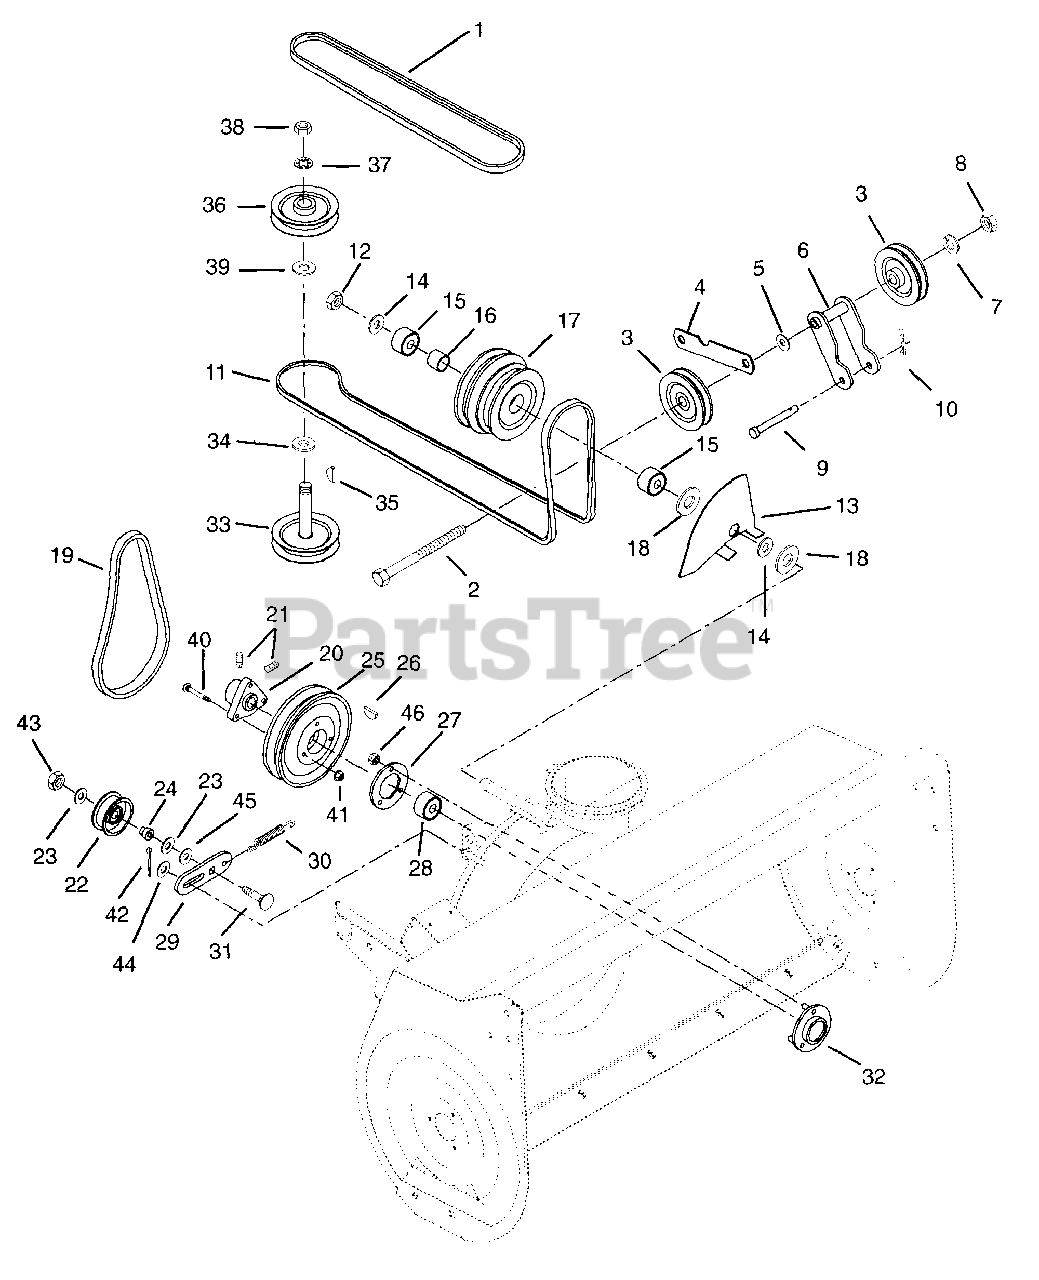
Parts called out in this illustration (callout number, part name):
1	V-BELT, HA-RAW EDGE
2	@BLT-HEX .38-16X5.00 GR5 YWZC
3	IDLER-V 4.00 X .38 NWHAMSHR
4	STRAP
5	WSHR-FL-STL .754X1.000X.032 YZ
6	IDLER BRACKET
7	@WSHR-LK .38X.094 REG YWZC
8	@NUT-HEX .38-16 YWZC
9	CLEVIS PIN 3/8X3.0 YWZC
10	PIN-HAIR INT .08X.38X1.42 YWZC
11	V-BELT, HA-WRAPPED
12	NUT-LK-CTR .75-10 PL
13	SHIELD
14	WSHR-FL-STL .781X1.250X.059 PL
15	BRG-BALL .750X1.781X.61
16	SPACER 1.00 X .770/.760 X .813
17	SHEAVE, DOUBLE
18	WSHR-FL-STL .781X1.500X.188
19	V-BELT, 4L-RAW EDGE
20	HUB
21	SCR-SET .31-18X.38 SKHCUPDL
22	IDLER
23	WSHR-FL-STL .390X.88X.18 YWZC
24	SPACER -FLANGED .390X.500X.781
25	PLY-V 9.0 X 1.25 3BLT
26	KEY-WDRF .188X.875X.375 SAE11
27	BEARING FLANGE
28	BRG-BALL1.0X2.0X.56
29	IDLER ARM
30	SG-TENS .090X.75X3.50 WLD 34
31	@BLT-RDHDSQNK .38-16X1.75 G5YZ
32	BEARING FLANGE
33	SPINDLE SHAFT
34	SPACER .755X1.250X.370
35	KEY-WDRF .188X.75X.313 SAE 9
36	PLY-V 4.50 X .75 W/KEY SALEM
37	WSHR-LK-INT .750 YWZC
38	NUT-JAM .75-10 YWZC
39	@WSHR-LK .75X.188 REG YWZC
40	BLT-SERRDHD SL .31-18X.87 PL
41	@NUT-SPNLK-FLG .312-18 YWZC
42	@PIN-CTR .12X.75 EXTPRSQCT YWZ
43	@NUT-LK-CTR .38-16 YWZC
44	WSHR-FL-STL .382X.812X.023YWZC
45	@WSHR-FL-STL.438X1.00X.083 YWZ
46	@WSHR-FL-STL.38X.875X.083 YWZC
